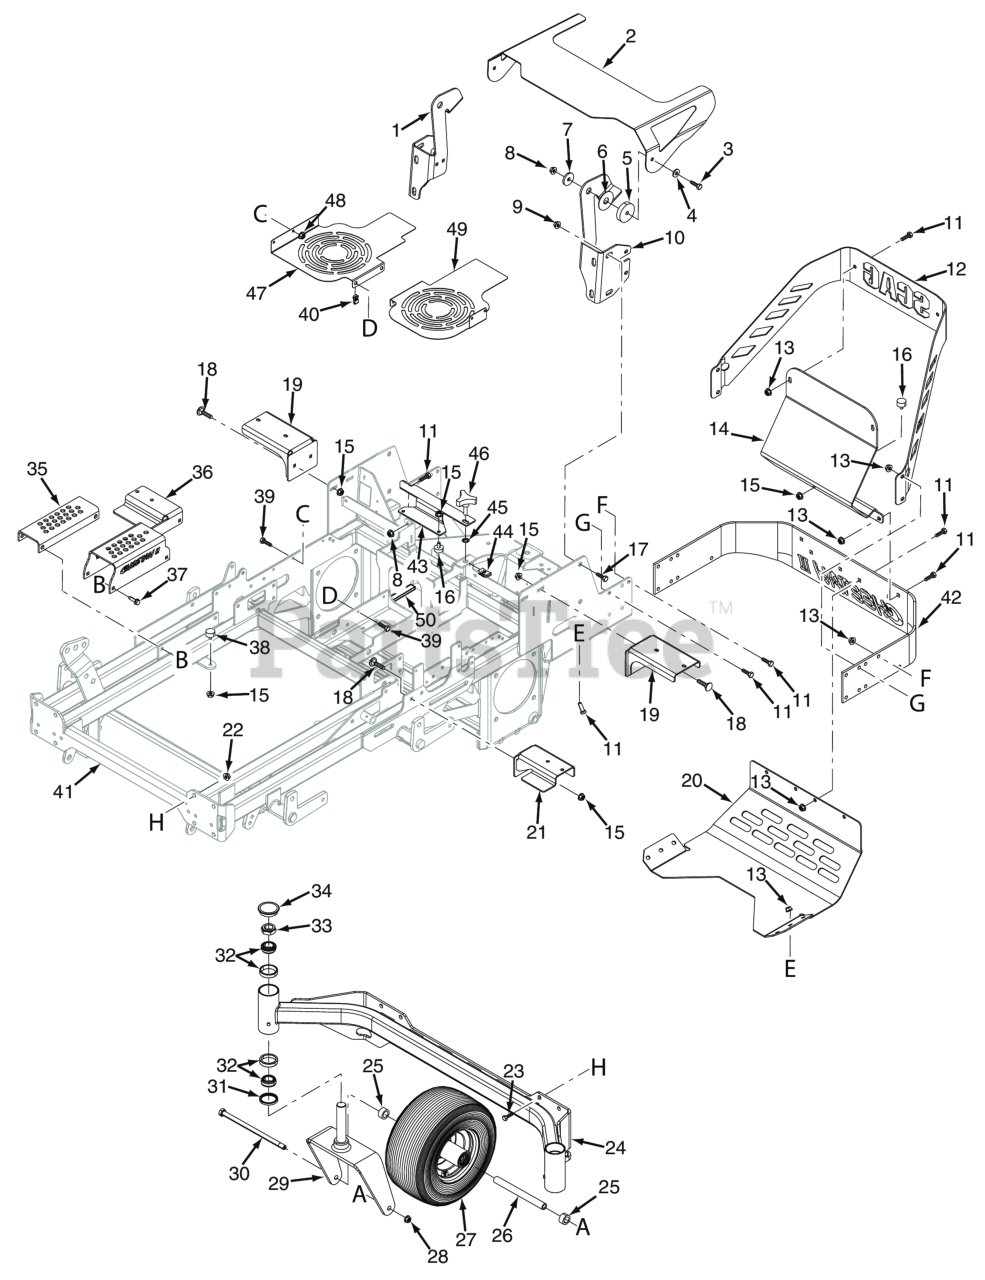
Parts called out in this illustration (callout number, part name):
1	ROPS Mount, RH, 29CV-EFI
2	Hood, SCZII
3	Bolt, Hex Head 3/8-16 x 1-3/4" (Kohler EFI)
4	Flatwasher, 3/8" Special (.391 x .938 x .105)
5	Spacer, Hood
6	Disc, Anti-Friction
7	Flatwasher, 3/8-.406 x 1-1-1/2 x 7 Gauge
8	HEX NUT, ELASTIC STOP LOCK, 3/8-16
9	Nut, Elastic Stop 1/2-13, (STT-52 & STTII-52)
10	ROPS Mount, LH, 29CV-EFI
11	Bolt, Hex Head, 3/8-16 x 1 Gr. 5
12	Engine Cover, Sides
13	NUT, 3/8-16 SERRATED FLANGE HEX HEAD
14	Engine Cover, Rear
15	Nut, Serrated Flange 5/16-18 (Right Front Engine Mounting, Briggs and Kohler Only)
16	Bumper, Rubber 5/16-18 x 5/8"
17	Bolt, Hex Head 1/2-13 x 1-1/4"
18	Bolt, 5/16-18 x .75 RHSN Carriage
19	Mounting Bracket, Fuel Tank Rear
20	Skid Plate, Rear
21	Mounting Bracket, Fuel Tank Front
22	Nut, 7/16-14 Flange Elastic Stop
23	BOLT, HEX HEAD, 7/16-14 X 1-1/4
24	Caster Support Weldment, 61V
24	Caster Support Weldment, 72V
25	Spacer, Caster Wheel
26	Sleeve, Caster Wheel (61V, 72A/VS)
27	Caster Wheel Assembly 61V (LH)
27	Rim Assembly, 61A & 72A (Inc. item 55)
28	HEX LOCKNUT, ELASTIC STOP, 1/2-13
29	Yoke Weldment
30	Bolt, Hex Head 1/2-13 x 9-1/2" (61V & 72A/VS)
31	Seal, 2.00" O.D. x 1.625" Bore
32	BEARING & CUP, TAPERED SPINDLE
33	Nut, Hex Elastic Stop 1.0"-14
34	Cap, Grease
35	Adjustment Bracket, Lower Cut Height
36	Bracket, Upper Cutting Height
37	Bolt, Hex Wshr Head 5/16-18 x 1-1/4"
38	Bumper, Rubber
39	Bolt, Serrated Flange Hex Head 1/4 x 20 x 3/4"
40	Bolt, Hex Head 3/8-16 x 1"
41	Frame w/ Decals
42	Bumper, Rear
43	Cover, Battery Box
44	U-Nut, 3/8-16 (short)
45	Nut, Push-On - 3/8" Dia.
46	Knob, w/stud 3/8-16 x 1-1/4"
47	Fan Cover, RH
48	NUT, 1/4-20 SERRATED FLANGE HEX HEAD
49	Fan Cover, LH
50	PAD, BATTERY SUPPORT
